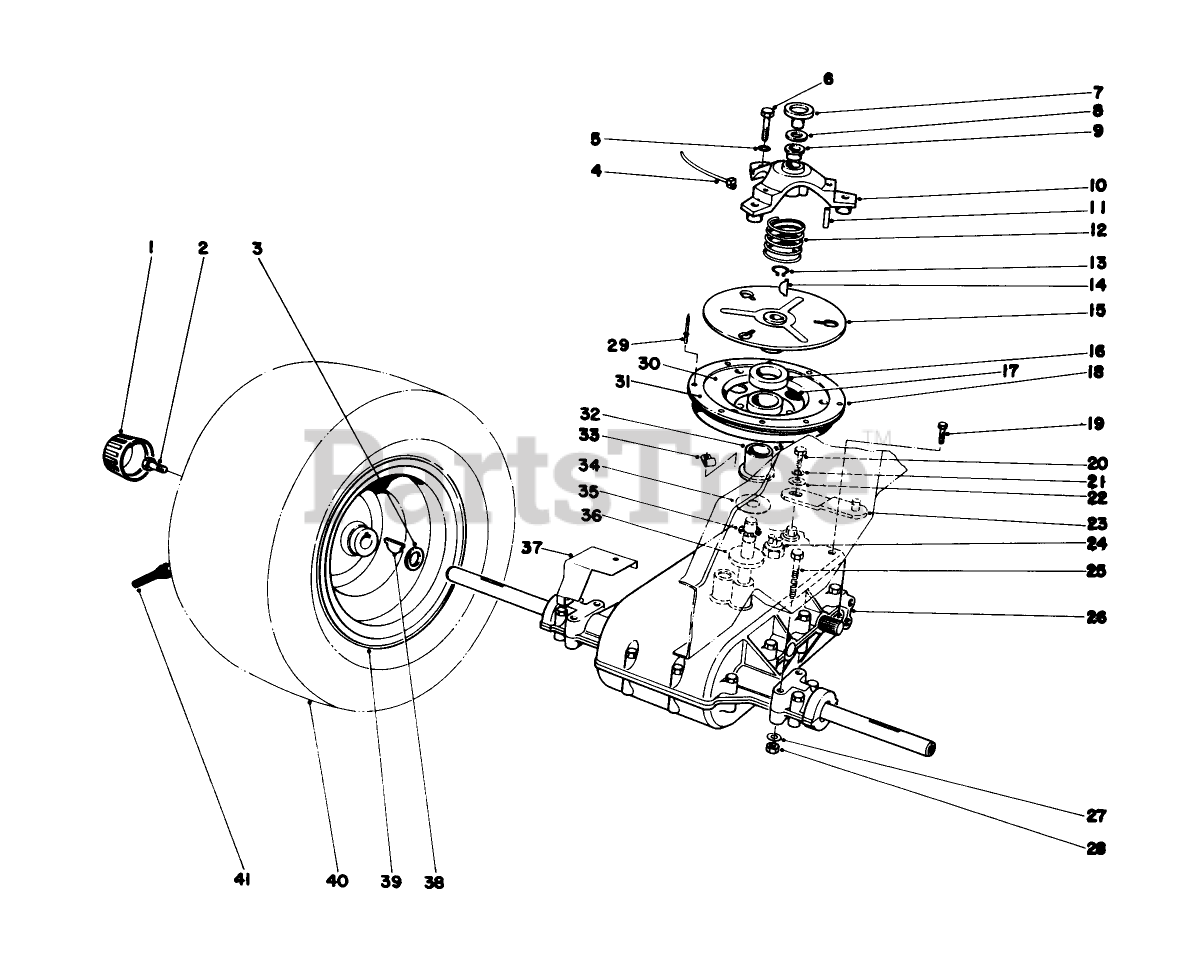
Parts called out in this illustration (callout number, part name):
3	SPACER-WHEEL
4	TIE-MOUNT, PUSH
5	WASHER-LOCK
6	SCREW-HH
7	CLUTCH CAP
8	THRUST RACE
9	BUSHING-FLANGE
11	NEEDLE BRG
13	RING-SNAP, EXTERNAL
14	KEY-WOODRUFF
16	WASHER FELT
18	SHEAVE ASM
19	SCREW-THD ROLL, HWH
20	SCREW-HH
21	WASHER-LOCK
22	WASHER-FLAT
24	NEUTRAL SWITCH
25	SCREW-HH
27	WASHER-PLAIN
28	NUT-LOCK, CONE
29	RIVET-POP
33	CLIP-FUEL LINE
34	THRUST WASHER
35	NEEDLE BRG
